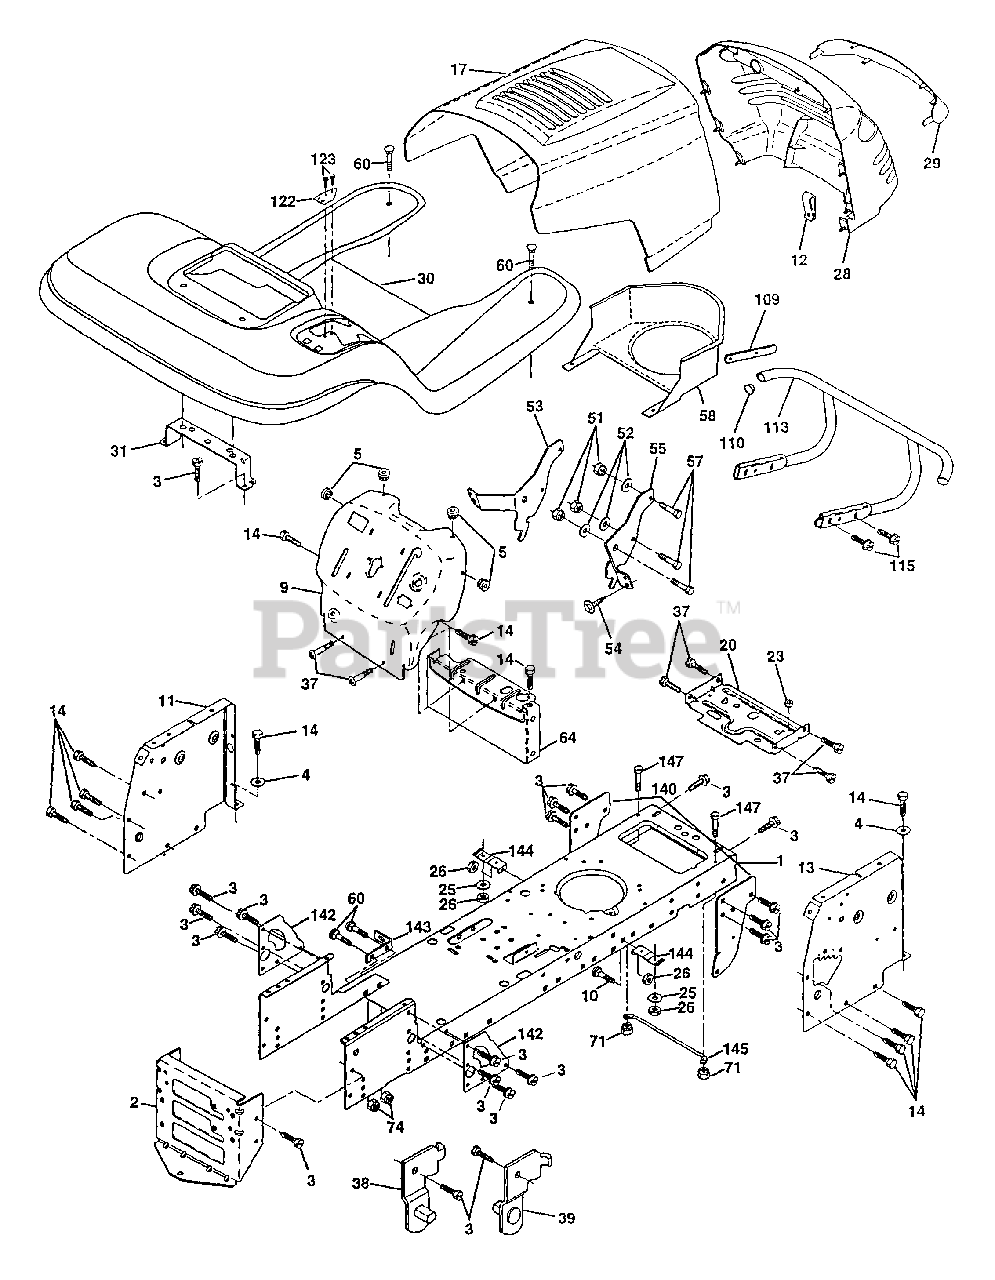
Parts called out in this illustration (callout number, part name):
1	Chassis Weldment
2	Drawbar, Stretch (AYP part number)
3	Screw Thdrol 3/8-16 x 3/4 Ty-tt
4	Washer 13/32 x 3/4 x 16 Ga.
5	Bumper Hood/Dash
9	Dash P/L E A Hm NC Sym
10	Bolt Carriage 3/8-16 x 1 (AYP part number)
11	Panel Dash Lh (AYP part number)
12	Clip Tinnerman
13	Panel Dash Rh
14	Screw Thdrol 3/8-16 x 1/2 Ty-tt
17	Hood LT/PL
20	Plate Mtg Battery Fuel Tank Fr (AYP part number)
23	Bushing (AYP part number)
25	Washer 13/32 X 13/16 X 12 Ga
26	Nut Lock Hex W/Ins 3/8-16 Unc
28	Grille LT/PL
29	Lens LT/PL
30	Fender Footrest STLT Pnt
31	Bracket Support Fender
37	Screw Thdrol 6/16-18 x 1/2 TYT
38	Bracket, Asm. Pivot, L.H., Mower Rear
39	Bracket, Asm. Pivot, R.H., Mower Rear
51	Nut Lock Hex W/Ins 1/4-20
52	Washer 9/32 x 7/8 x 16 Ga.
53	Bracket Grukke Lh
54	Screw Lock Spider #8 x 7/8
55	Bracket Grille Rh
57	Bolt Hex 1/4-20 x 3/4 (AYP part number)
58	Air Duct Engine P/L
60	Bolt Rdhd Sqnk 3/8-16 unc x 3/4
64	Dash Lower STLT
71	Nut Crownlock 1/4-20 Unc (AYP part number)
74	Nut Crownlock 3/8-16 UNC
109	Bracket Extension Bumper (AYP part number)
110	Plug Plastic
113	Bumper Asm
115	Screw Thdrol 3/8-16 x 1-1/4
122	Bracket Shift STLT
123	Screw TT #10-32 5-3/8 Flange
140	Bracket Suspension Front
142	Plate Reinforcement STLT
143	Bracket Swaybar Chassis (AYP part number)
144	Bracket Pnt Footrest STLT (AYP part number)
145	Rod Pivot Chassis/Hood
147	Bolt Hex Hd 1/4-20 Unc x 3/4
